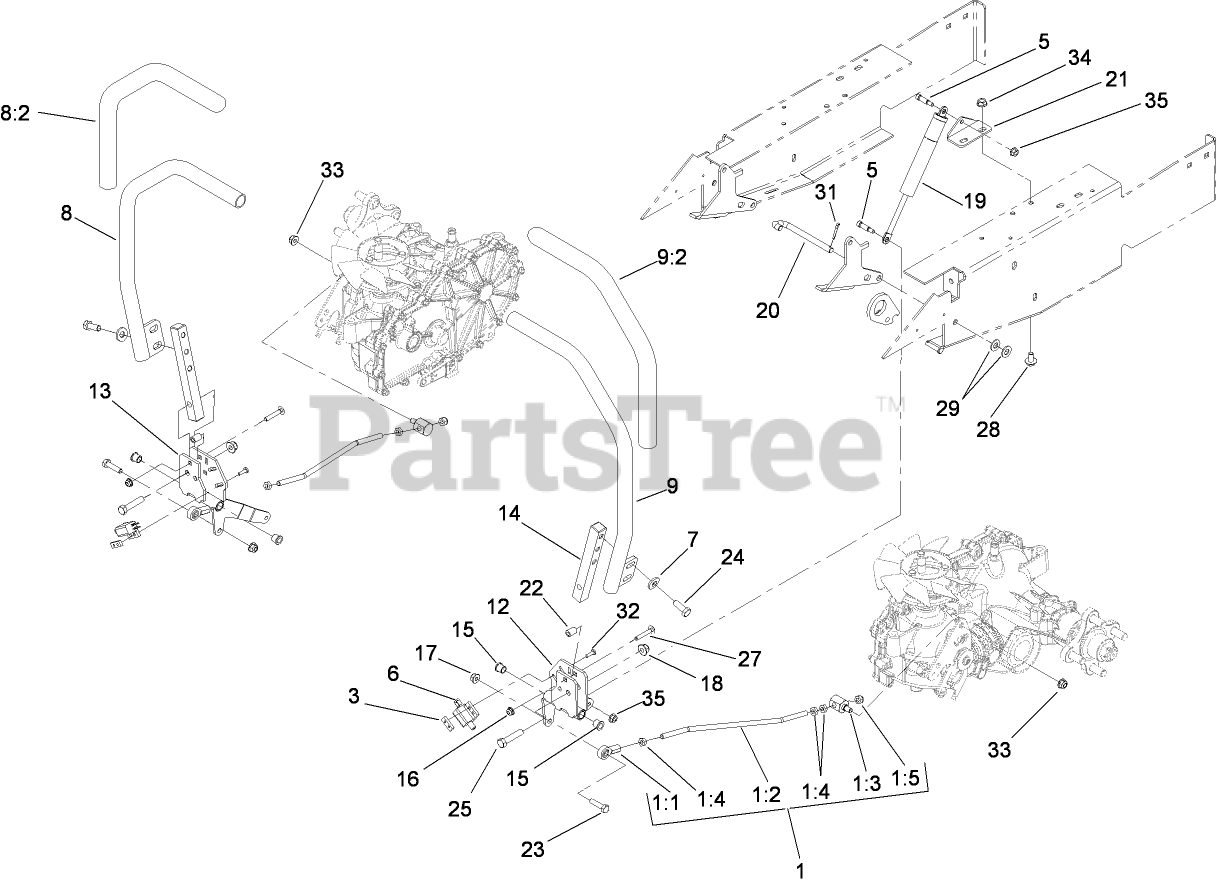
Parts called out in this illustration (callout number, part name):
1	STEERING ROD ASM
1:1	BALLJOINT-RH
1:2	ROD-STEERING, LH
1:3	TRUNNION
1:4	NUT-JAM
1:5	NUT-LOCK
3	PLATE-TAPPED
5	SCREW-HSH
6	SWITCH-POLE, SINGLE
7	WASHER-BELLEVILLE
8	RH CONTROL LEVER ASM
8:2	GRIP-FOAM
9	LH CONTROL LEVER ASM
9:2	GRIP-FOAM
12	CONTROL-STEERING, RH
13	CONTROL-STEERING, LH
14	MOUNT-POST, LEVER
15	BEARING
16	NUT-HF
17	NUT-HF, NI
18	NUT-HF, NI
19	DAMPER-CONTROL, MOTION
20	SHAFT-PIVOT, CONTROL
21	BRACKET-DAMPER
22	SPACER
23	SCREW-HH
24	SCREW-HH
25	SCREW-HH
27	SCREW-CARR
28	SCREW-HHF
29	WASHER-FLAT
31	PIN-COTTER
32	SCREW-PPH
33	NUT-HF, NI
34	NUT-HF
35	NUT-HF
